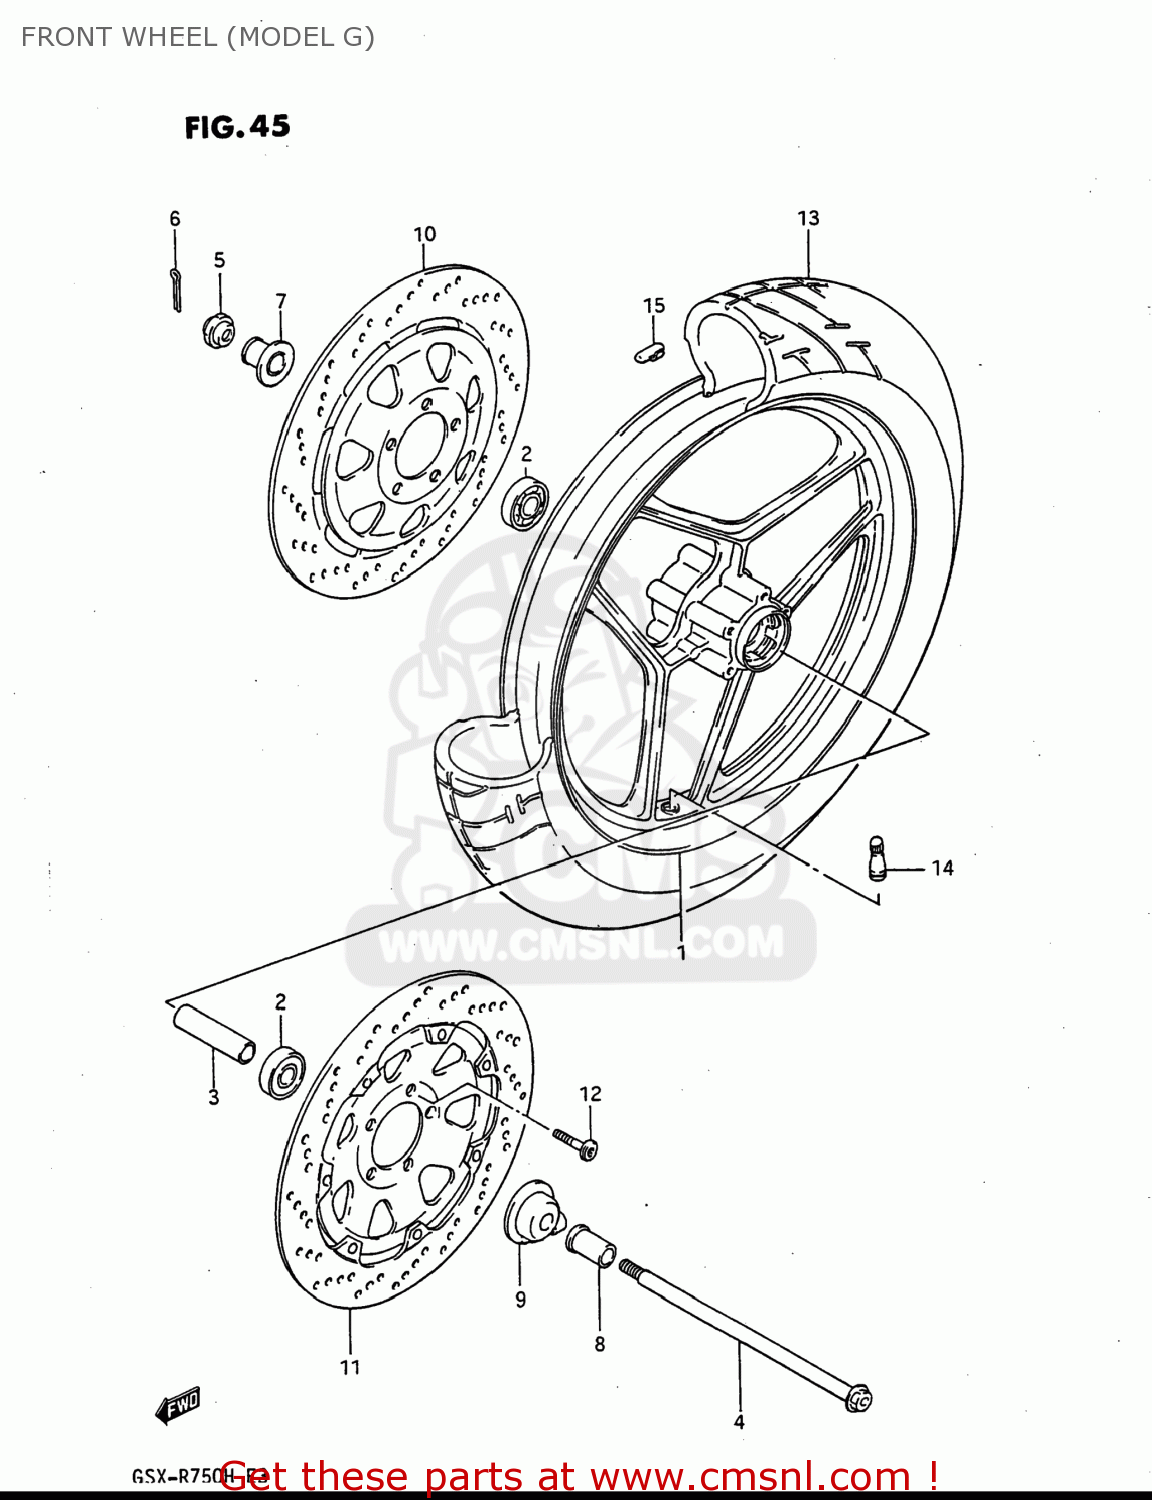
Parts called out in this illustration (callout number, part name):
1	WHEEL,FRONT (2.50X18)
2	BEARING
3	SPACER(15.3X21.7X77)
4	AXLE,FR
5	NUT (12MM)
6	COTTER PIN
7	SPACER,FR HUB BEARING,R
8	SPACER
9	BOX ASSEMBLY,SPEEDOMETER GEAR
10	DISC,BRAKE
11	DISC,BRAKE
12	BOLT
13	TIRE,FRONT
14	VALVE,TIRE
15	BALANCER,WHEEL
